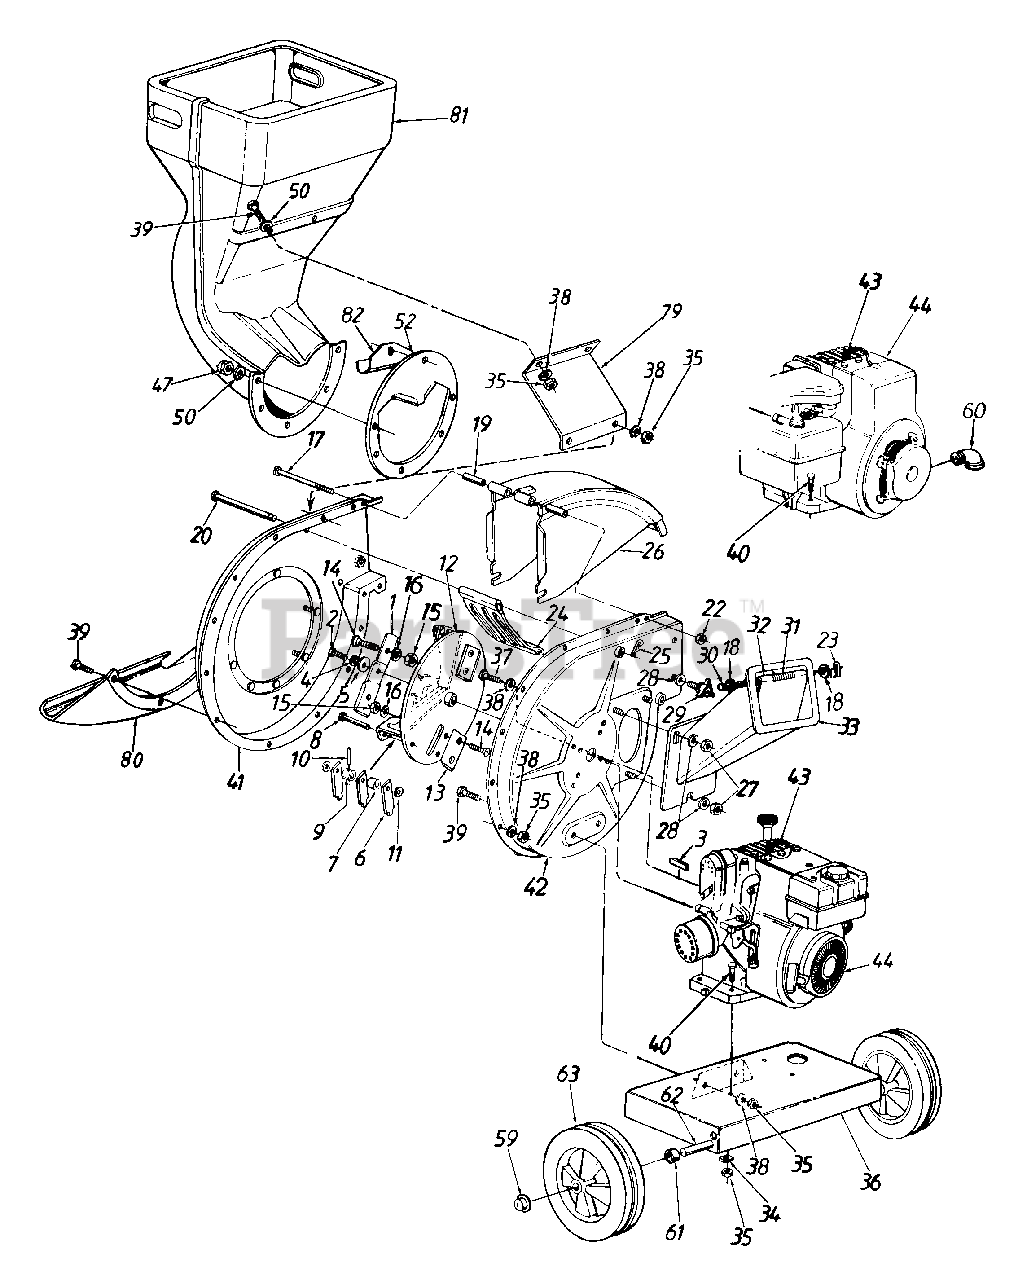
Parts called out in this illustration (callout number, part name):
1	Blade
2	Hex Patch Bolt 3/8 - 24 x 2" Lg. (Gr. 8)
2	Hex Patch Bolt 3/8 - 24 x 2.25" (Gr. 8)
3	Sq. Key 1/4 x 2.0" Lg.
4	L-Wash. 3/8" I.D. H.D.
5	Fl-Wash. .406" I.D. x 1.25" O.D. Hdn.
6	Flail
7	Flail Spacer
8	Clevis Pin .496" Dia.
9	Flail Spacer w/.160" Dia. Hole
10	Spring Roll Pin 1.12" Lg.
11	Fl-Wash. .531" I.D. x .94" O.D.
12	Impeller Ass'y. Comp.
13	Chipper Blade
14	Flat Hd. Scr. 5/16 - 24 x .75" Lg.
15	Hex Top L-Nut 5/16 - 24 (Gr. 5)
16	L-Wash. 5/16" I.D.
17	Hex Bolt 1/4 - 20 x 3.75" Lg.
18	Fl-Wash. .281" I.D. x .50" O.D.
19	Chute Hinge Spacer 1.66" Lg.
20	Clevis Pin .5" Dia. x 4.62" Lg.
22	Hex Ctr. L-Nut 1/4 - 20 Thd.
23	Cotter Pin
25	Internal Cotter Pin 3/8" Dia.
27	Hex Nut 5/16 - 18 Thd. (Gr. 5)
28	Bell-Wash. .345" I.D. x .88"
29	Hand Knob
30	Chipper Door Rod
31	Torsion Spring 1.14" Lg.
35	Hex Nut 5/16 - 18 Thd. (Gr. 5)
37	Hex Bolt 5/16 - 24 x .75" Lg.
38	L-Wash. 5/16" I.D.
39	Hex Bolt 5/16 - 18 x .75" Lg. (Gr 5)
40	Hex Bolt 5/16 - 18 x 1.5" Lg.
44	Engine
47	Elastic Lock Nut 5/16 - 18 Thd.
50	Fl-Wash. 5/16" I.D.
52	Back-Up Plate
59	Push Cap 5/8" Dia. Rod
60	Drain Elbow (5 HP B&S)
61	Spacer .64" I.D. x .38" Lg.
62	Shredder Axle
63	Wheel Ass'y. Comp.
81	Leaf Hopper
